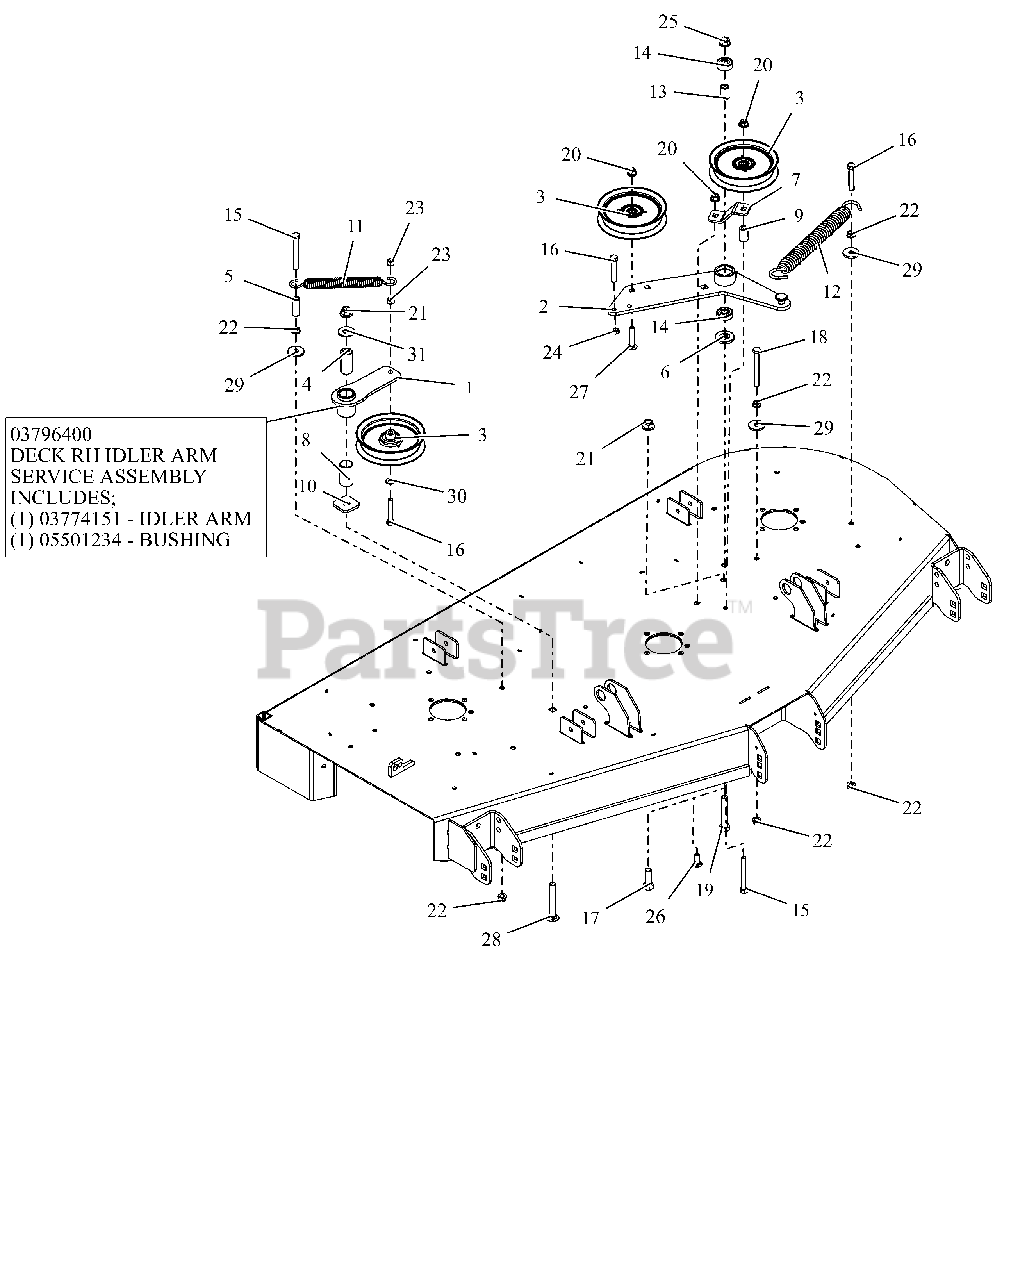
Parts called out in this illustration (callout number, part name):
1	WMT, IDLER ARM - BLACK
1	ASM, IDLER ARM (DECK)
2	DECK PTO IDLER ARM WLDMT - BLK
3	IDLER, FLAT 5.00"
4	BSHG, SPCR .502X.997X2.03 PM
5	SPACER, .375IDX.625ODX1.66 PM
6	SPACER, IDLER ARM
7	PTO FIXED IDLER MTG BRKT -RED
8	BSHG, 1.00X1.125X1.937
9	BUSHING, SLV .380X.750X1.190
10	WSHR-FLT .640X1.75X.250
11	SPRING, EXTENSION
12	SPRING, EXTENSION
13	SPACER .510 X .75 X 1.1485
14	BRG-BALL .500X1.38X.437
15	BLT, HEX .38-16X3.25 G5 ZCC
16	BLT,HEX .38-16X2.25 G5 ZCC
17	BLT,HEX .50-13X1.50 G5 ZCC
18	BLT, HEX .38-16X3.50 G5 ZCC
19	BLT, HEX .50-13X3.00 G5 ZCC
20	NUT,NYL-FLG .38-16 GF ZCC
21	NUT,NYL-FLG .50-13 GF ZCC
22	NUT, SPNLK-FLG .38-16 G5 ZCC
23	NUT-LK-CTR .38-16 ZC120
24	NUT-JAM .375-16 G2 ZCC
25	NUT-LK-CTR-FLG .500-13 GG ZCC
26	BLT,RHSSN .38-16X1.00 G5 ZCC
27	BLT,RHSSN.375-16X2.00 G5 ZCC
28	BLT, RHSN .50-13X3.50 G5 ZCC
29	WSHR,FLT .406X1.375X.135 ZCC
30	WSHR,FLT .406X.812X.065 ZCC
31	WSHR,FLT .563X1.375X.109 ZCC
